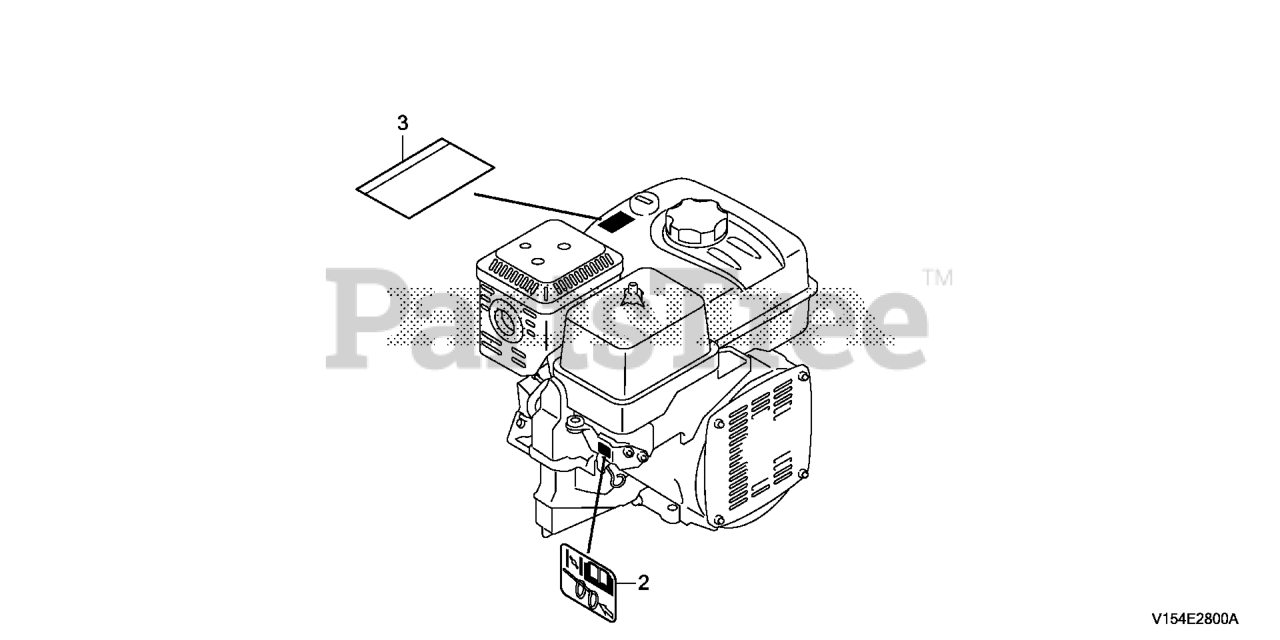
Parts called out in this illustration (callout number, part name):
1	MARK, FUEL WARNING COMBINATION (ENGLISH)
2	MARK, CHOKE
3	MARK, EX. CAUTION (ENGLISH)
